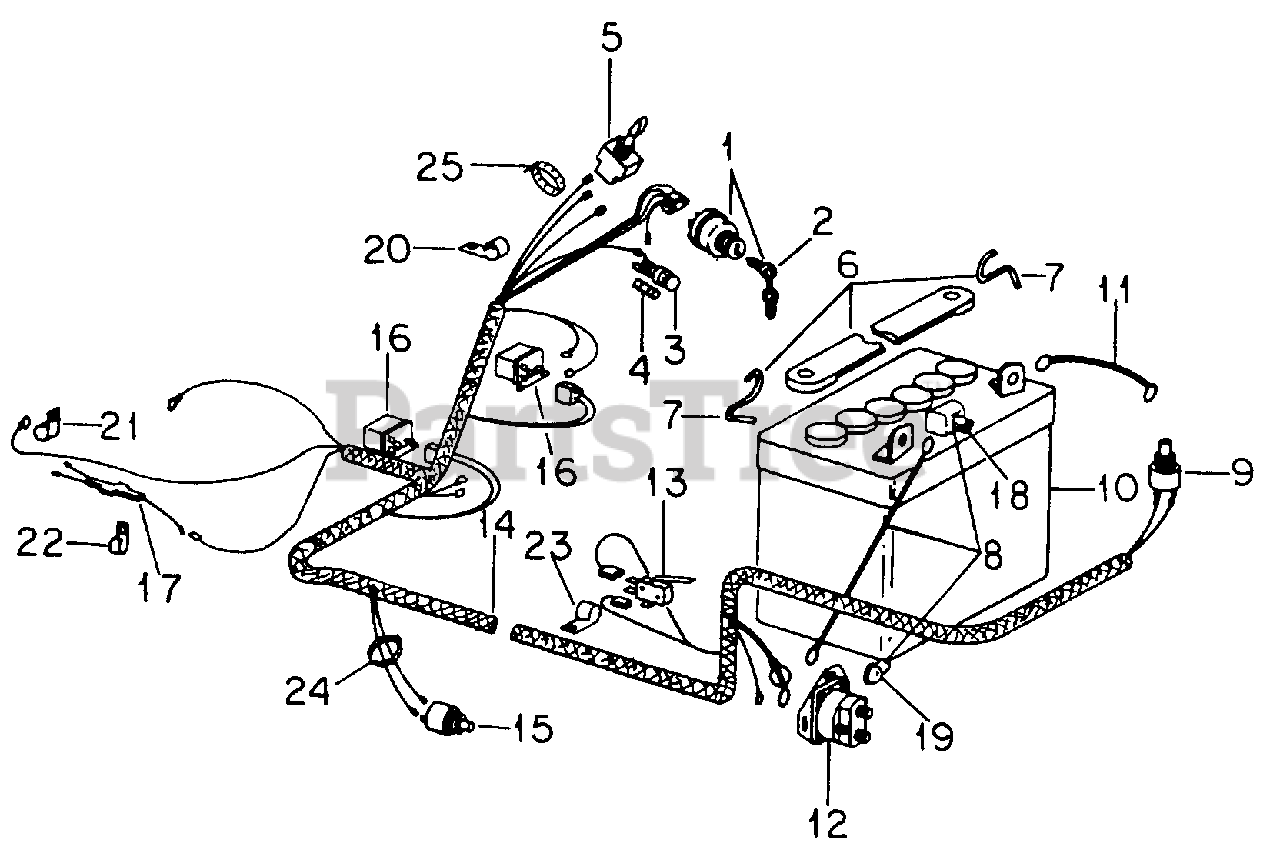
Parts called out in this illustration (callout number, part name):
1	Switch Assy, Battery Ignition Key
2	Key, Ignition Switch
3	Holder Assy, Fuse
4	Fuse, 15 Amp
5	Switch, IPTO
6	Strap, Battery
7	Hook, Battery Strap
8	Cable, Battery, Positive
9	Switch, Neutral Start, Normally Closed
10	Battery, IH Low Maintenance, 12 Volt
11	Cable, Battery, Negative
12	Switch, Magnetic, Solenoid
13	Switch, Reverse Cut-Out
14	Harness, Main Cable
15	Switch, Neutral Start, Normally Open
16	Relay
17	Diode Assy
18	Cover, Battery Terminal
19	Insulator, Terminal Boot
20	Clip, Cable
21	Clip, Cable, IPTO Clutch
22	Clip, Cable, Heat Shield & Frame
23	Clip, Cable, LH Channel at X Member
24	Strap, Cable Tie
25	Strap, Cable Lock
